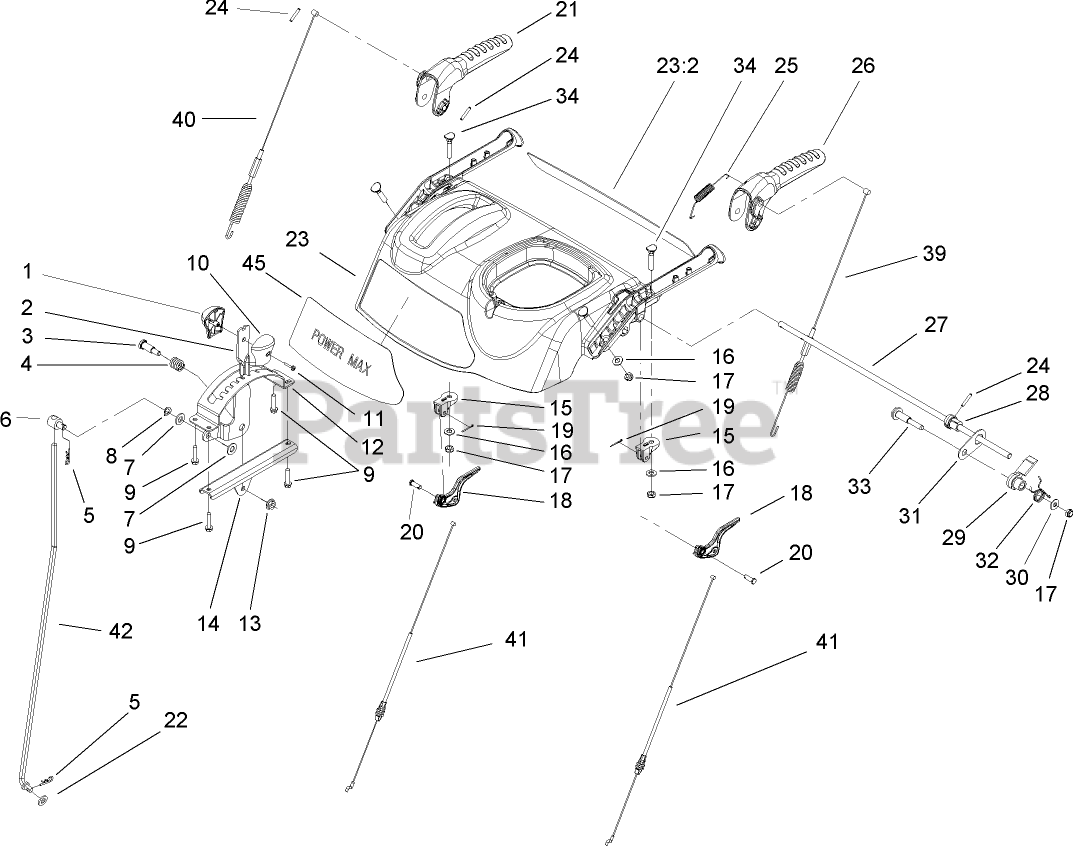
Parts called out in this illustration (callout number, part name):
1	KNOB-SHIFT, RH
2	SELECTOR-SPEED
3	SCREW-SHOULDER
4	SPRING-COMPRESSION
6	TRUNNION
7	WASHER-FLAT
8	WASHER-SPRING
9	SCREW-PLASTITE
10	KNOB-SHIFT, LH
11	SCREW-PPH
12	GUIDE-SELECTOR, SPEED
13	NUT-HF
14	MOUNT-SELECTOR, SPEED
15	MOUNT-LEVER, CLUTCH
16	WASHER-FLAT
17	NUT-LOCK, NI
18	LEVER-CLUTCH
19	PIN-COTTER
20	PIN-CLEVIS
21	LEVER-AUGER
22	WASHER-FLAT
23	CONTROL PANEL ASM
24	PIN-SPRING
25	SPRING-TENSION
26	LEVER-TRACTION
27	ROD-LOCKOUT
28	CAM-LOCKOUT
29	LATCH-LOCKOUT
30	WASHER-FLAT
31	LINK-LOCKOUT
32	SPRING-TORSION
34	SCREW-HANDLE
41	CABLE-CLUTCH
45	DECAL-PANEL, CONTROL
